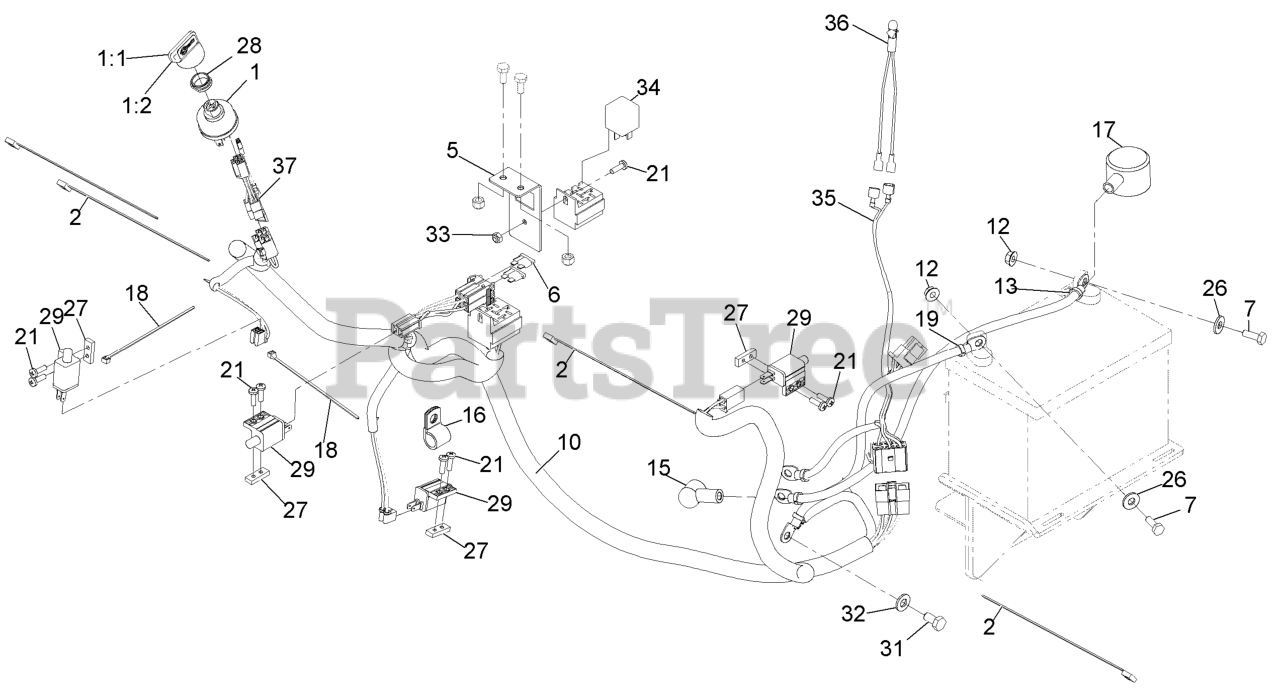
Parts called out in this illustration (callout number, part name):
1:1	KEYS-IGNITION (SPARE PAIR
1:2	KEY-IGNITION
2	TIE-PLASTIC
5	BRACKET-FUSE AND RELAY
6	FUSE-BLADE TYPE, 20 AMP
7	SCREW-HH
10	HARNESS-WIRE, TTS
13	ASM,POSITIVE BATTERY CABL
15	INSULATOR-SOLENOID
16	CLIP-LOOM
17	INSULATOR-BATTERY
18	TIE-CABLE
19	CABLE-BATTERY, NEGATIVE
21	SCREW-PPH
26	WASHER-FLAT
27	PLATE-TAPPED
28	NUT-SWITCH, IGNITION
29	SWITCH-OPEN, NORMALLY
31	SCREW-HH
32	WASHER-PLAIN
33	NUT-LOCK, NI
35	HARNESS, MIL
36	INDICATOR-LED, RED
37	HARNESS, LP PIGTAIL
